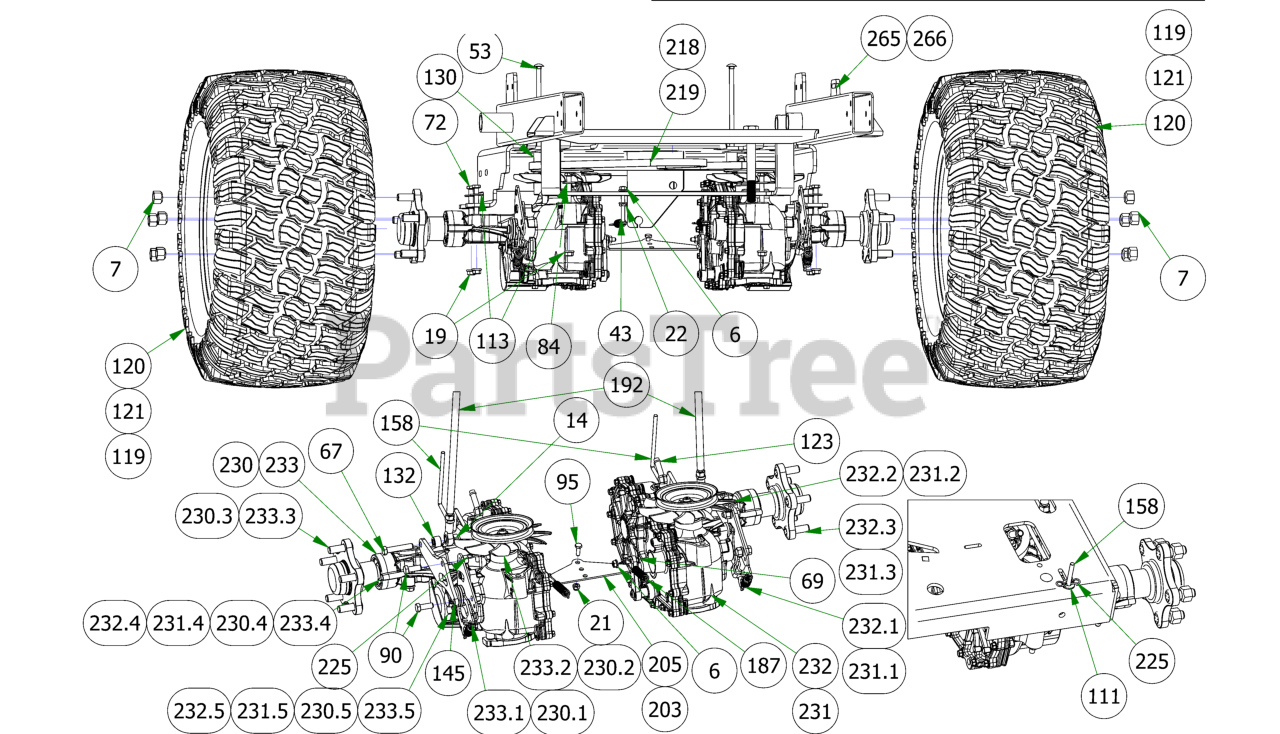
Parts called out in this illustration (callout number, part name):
6	1/4-20 NYL INSERT FLANGE LOCKNUT ZINC
7	Acorn Lug Nut
14	3/8-16 HEX NUT ZINC
19	5/16-18 NYLON INSERT FLANGE LOCKNUT ZINC
21	1/4-20 NYLON INSERT LOCKNUT ZINC
22	1/4-20 HEX SERRATED FLANGE NUT HARD/ZINC
31	1 1/2 x 3 Frame Plug
43	1/4-20 X 2 HEX CAP SCREW (GR.5) ZINC
53	5/16-18 X 6 CARRIAGE BOLT (GR.5) ZINC
67	3/8-16 X 2 HEX CAP SCREW (GR.5) ZINC
69	1/4-20 X 1 HEX CAP SCREW (GR.5) ZINC
72	5/16-18 X 3 HEX CAP SCREW (GR.5) ZINC
84	5/16-18 X 2-1/2 HEX CAP SCREW (GR.5) ZINC
90	3/8-16 X 1 GR 5 Hex Bolts Zinc
95	1/4-20 X 3/4 HEX CAP SCREW (GR.5) ZINC
104	3/8 SPLIT LOCKWASHER ZINC
111	1/4 USS FLAT WASHER (3/4 OD) ZINC
113	5/16 USS FLAT WASHER (7/8 OD) ZINC
119	23x9-12 Reaper Turf Tire & Wheel Assembly
120	21/7x10 Reaper Tire-36 Revolt
121	23x11-12 Reaper Turf Assembly
123	ZT Fitting, 3/8 x 3/8 45 Degree, 4603-6-6
130	2017 Transaxle Spacer
132	ACS Spacer 3/4x3/8x1/2
145	Control Arm Plate 2019 Stand On
158	2019 Stand On Neutral Rod
187	Brake Spring
192	2019 Revolt Push Rod Assembly
203	2020 36" Brake Bracket 2020 36" Stand On
205	Brake Bracket
218	2019 Renegade Pump Belt
219	2019 Stand On Pump Belt (Timken# 47-2827)
230	ZT Transaxle Right 3100
230.1	Gold Transaxle Spring
230.2	2021 ZT/Maverick Transaxle Fan/Pulley Kit
230.3	ZT Transaxle Wheel Hub
230.4	2021 ZT/Maverick Transaxle Seal Kit (ZT-2800)
230.5	ZT Hydraulic Filter
231	ZT Transaxle Left 3100
231.1	Gold Transaxle Spring
231.2	2021 ZT/Maverick Transaxle Fan/Pulley Kit
231.3	ZT Transaxle Wheel Hub
231.4	2021 ZT/Maverick Transaxle Seal (ZT-2800)
231.5	ZT Hydraulic Filter
232	Compact Outlaw/Revolt Transaxle Left 3400
232.1	Gold Transaxle Spring
232.2	Fan/Pulley Kit for CZT Also for the 050-0075-01
232.3	5 Bolt Hub Kit
232.4	Seal Kit for 3400 Transaxle fits the 050-6000-01 / 050-6001-01
232.5	ZT Hydraulic Filter
233	Compact Outlaw/Revolt Transaxle Right 3400
233.1	Gold Transaxle Spring
233.2	Fan/Pulley Kit for CZT Also for the 050-0075-01
233.3	5 Bolt Hub Kit
233.4	Seal Kit for 3400 Transaxle fits the 050-6000-01 / 050-6001-01
233.5	ZT Hydraulic Filter
265	2019 Stand On Frame
266	2020 36" Stand On Frame
